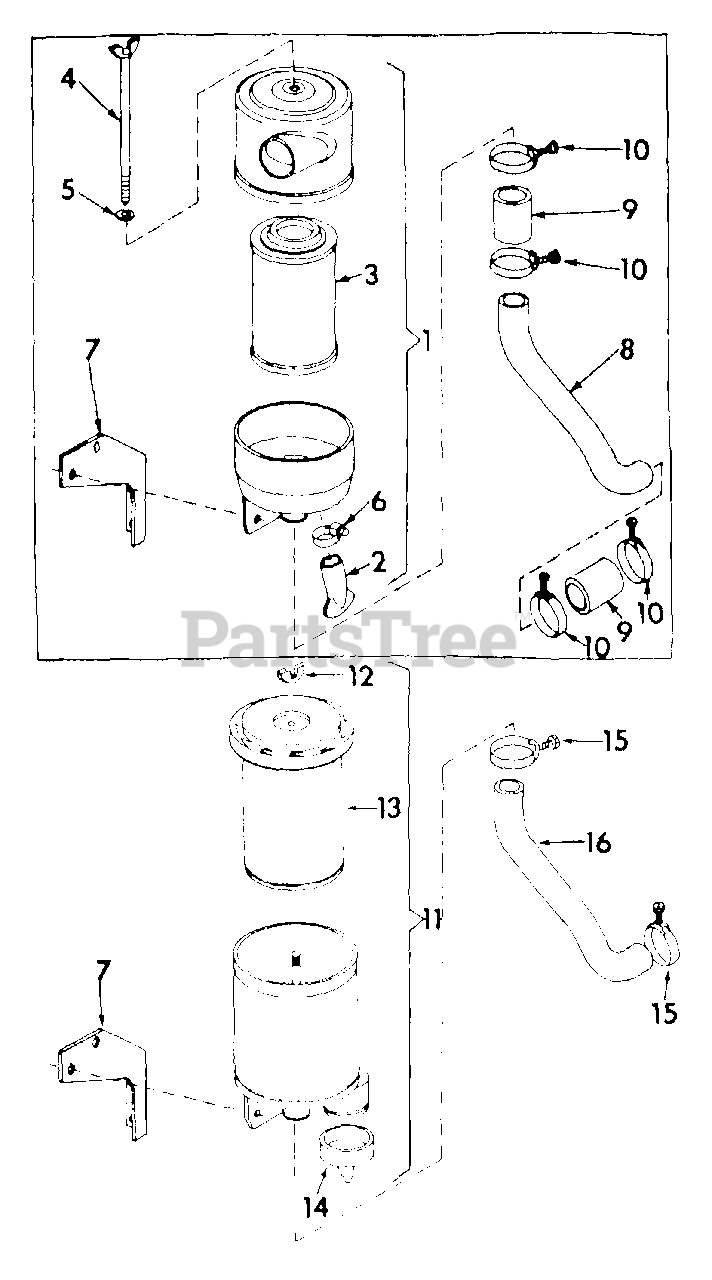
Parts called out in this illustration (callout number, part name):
1	CLEANER ASSY, 5-1/2 IN. DIAMETER DRY TYPE AIR
2	UNLOADER, AUTOMATIC DUST
3	ELEMENT ASSY, AIR CLEANER
5	WASHER, AIR CLEANER ELEMENT
7	BRACKET ASSY, AIR CLEANER
8	PIPE, AIR CLEANER TO CARBURETOR
9	HOSE, AIR CLEANER CONNECTION
10	CLAMP, AIR CLEANER HOSE
11	CLEANER ASSY, 5-1/4 IN. DIAMETER DRY TYPE AIR
13	ELEMENT W/WING NUT, AIR CLEANER
14	VALVE, RUBBER UNLOADER
15	CLAMP, AIR CLEANER HOSE
16	HOSE, AIR CLEANER TO CARBURETOR
